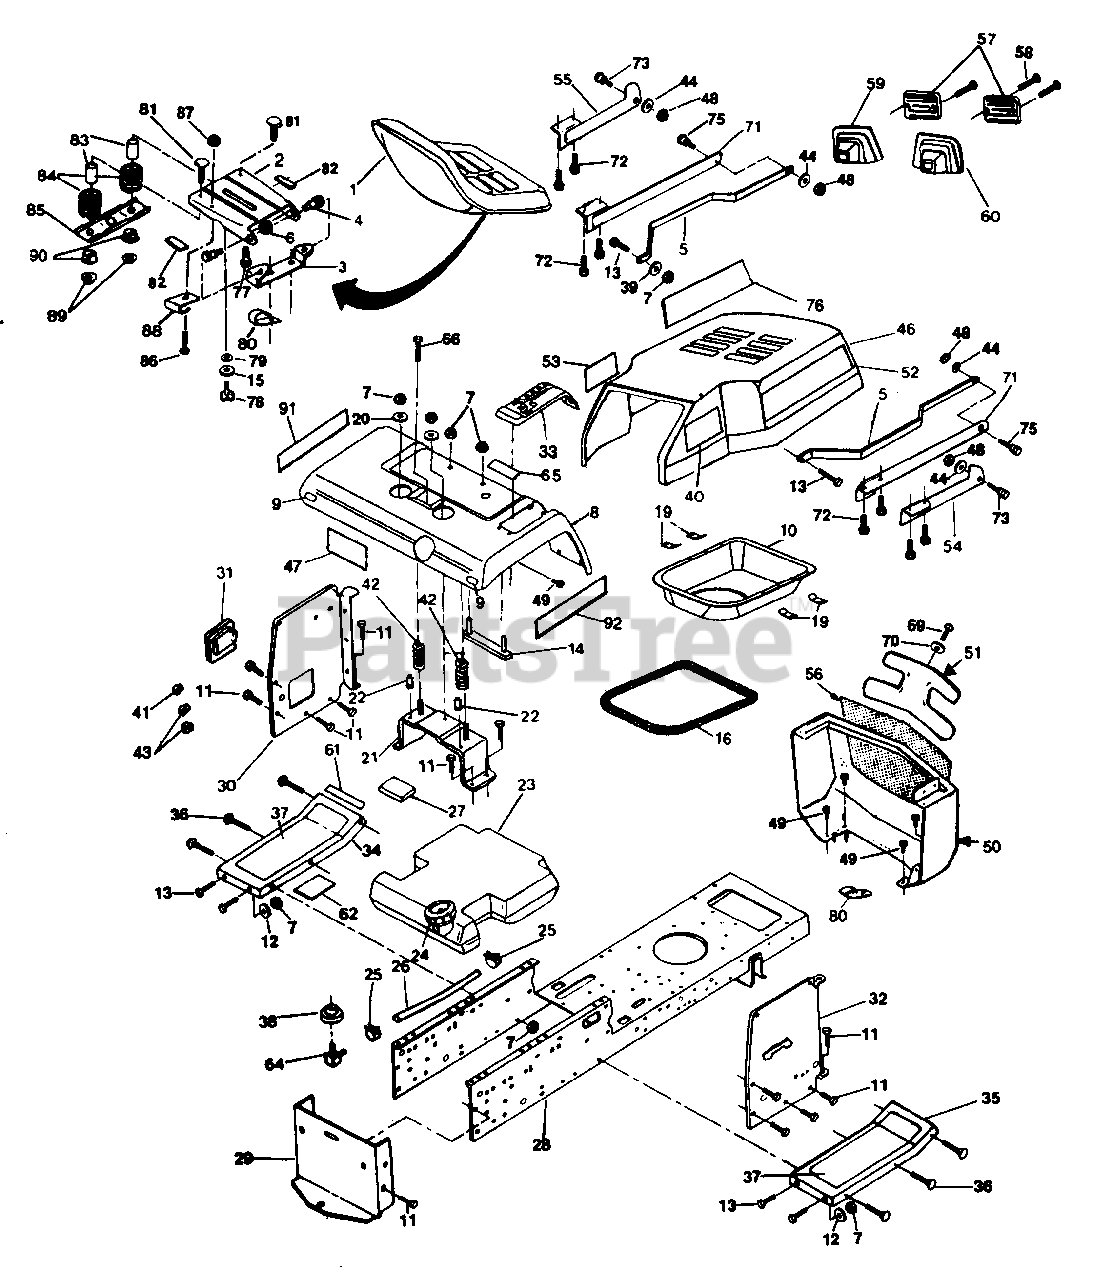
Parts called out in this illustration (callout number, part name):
1	Seat (AYP part number)
2	Seat Pan (AYP part number)
3	Seat Pivot Bracket (AYP part number)
4	Shoulder Bolt (AYP part number)
5	Grill Brace (AYP part number)
6	Locknut
7	Locknut
8	Fender (AYP part number)
9	Rear Reflector (AYP part number)
10	Engine Air Duct
11	Thread Roll Washer Hex Screw (AYP part number)
12	Washer (AYP part number)
13	Hex Bolt 3/8-16 x 3/4 (AYP part number)
14	Fender Strap (AYP part number)
15	Washer (AYP part number)
16	Foam Strip
19	Air Duct Bracket
20	Washer (AYP part number)
21	Fender Bracket (AYP part number)
22	Push Nut (AYP part number)
23	Fuel Tank (AYP part number)
24	Fuel Cap (AYP part number)
25	Hose Clamp (AYP part number)
26	Fuel Line (AYP part number)
27	Spacer Pad (AYP part number)
28	Chassis Assembly (AYP part number)
29	Drawbar (AYP part number)
30	L.H. Dash Panel (AYP part number)
31	Access Cover (AYP part number)
32	R.H. Dash Panel (AYP part number)
33	Console, Shifter (AYP part number)
34	L.H. Footrest (AYP part number)
35	R.H. Footrest (AYP part number)
36	Carriage Bolt (AYP part number)
37	Footrest Pad (AYP part number)
38	Bushing (AYP part number)
39	Washer 13/32 x 7/8 x 16 Ga. (AYP part number)
40	R.H. Decal (AYP part number)
41	Grommet (AYP part number)
42	Seat Spring (AYP part number)
43	Split Grommet (AYP part number)
44	Washer (AYP part number)
46	Hood (AYP part number)
47	Poulan Decal (AYP part number)
48	Crownlock Nut (AYP part number)
49	Thread Roll Washer Hex Screw (AYP part number)
51	Grill Insert
52	R.H. Hood Decal (AYP part number)
53	L.H. Decal (AYP part number)
54	R.H. Hinge Strap Assembly (AYP part number)
55	L.H. Hinge Strap Assembly (AYP part number)
56	Grill Screen (AYP part number)
57	Lens (AYP part number)
58	Pan Head Cross Screw (AYP part number)
59	L.H. Bezel (AYP part number)
60	R.H. Bezel (AYP part number)
61	Clutch/Brake Decal (AYP part number)
62	Drive Belt Decal (AYP part number)
64	Fuel Tank Stem (AYP part number)
66	Thread Roll Washer Hex Screw (AYP part number)
69	Slotted Hex Screw (AYP part number)
70	Washer (AYP part number)
71	Rear Hinge Strap Assembly (AYP part number)
72	Washer Head Hex Screw (AYP part number)
73	Shoulder Bolt (AYP part number)
75	Shoulder Bolt (AYP part number)
76	L.H. Hood Decal (AYP part number)
77	Shoulder Bolt (AYP part number)
78	Seat Knob (AYP part number)
79	Lock Washer 1/2 (AYP part number)
80	Fuel Line Clip (AYP part number)
81	Carriage Bolt (AYP part number)
82	Foam Strips (AYP part number)
83	Spacer (AYP part number)
84	Compression Spring (AYP part number)
85	Bracket Switch (AYP part number)
86	Pan Hd. Slotted Screw (AYP part number)
87	Keps Nut (AYP part number)
88	Insulated Clip (AYP part number)
90	Snap Bushing (AYP part number)
91	L.H. Fender Decal (AYP part number)
92	6-Speed Decal (AYP part number)
93	Washer (AYP part number)
94	Lock Washer (AYP part number)
95	Screw (AYP part number)
96	Flange Hex Locknut (AYP part number)
